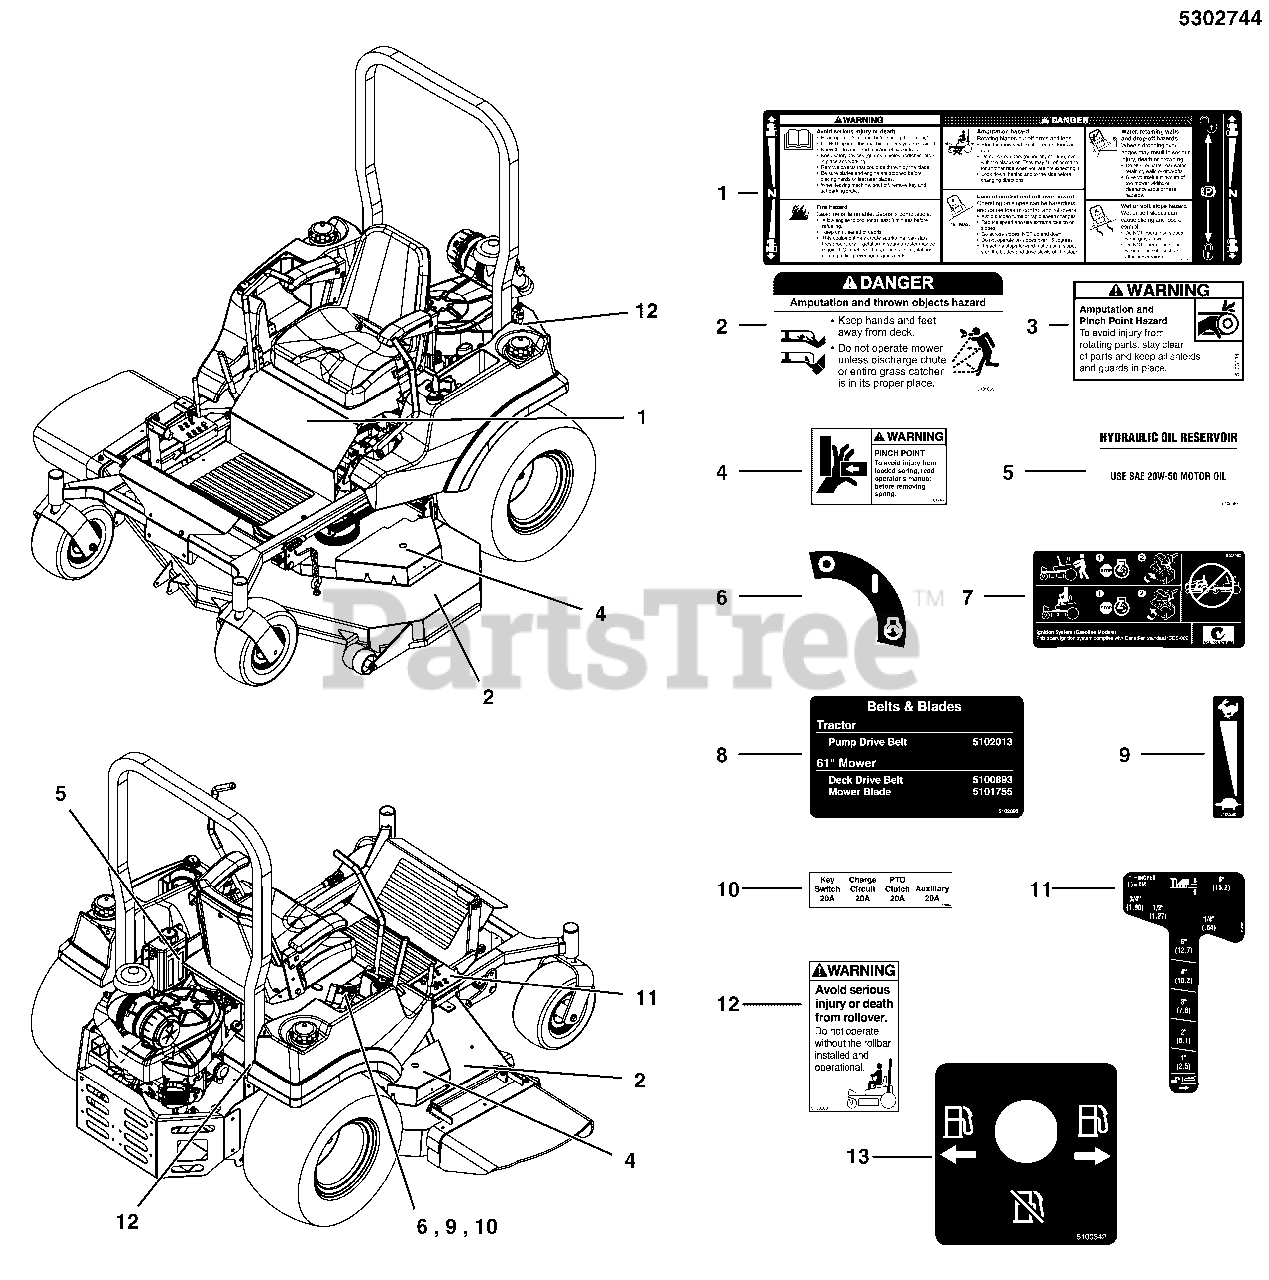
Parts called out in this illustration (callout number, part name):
1	DECAL, MAIN
2	DECAL-DANGER DO NOT OPERATE W/O DEFLECTR
3	DECAL, WARNING, HAND IN BELT, ENG ONLY
4	DECAL, PINCH POINT
5	DECAL, HYDRAULIC OIL, SAE 20W50
6	DECAL, IGNITION SWITCH
7	DECAL, TRANSAXLE RELEASE, S200XT
8	DECAL, BELT & BLADE, S200XT
9	DECAL, THROTTLE CONTROL
10	DECAL, FUSE LOCATION, 20-20-20-20
10	DECAL, FUSE LOCATION, 20-15-15-20
11	DECAL, DECK HEIGHT, 1-1/2 TO 6, S200XT
12	DECAL, WARNING, ROLL BAR
13	DECAL, FUEL VALVE
